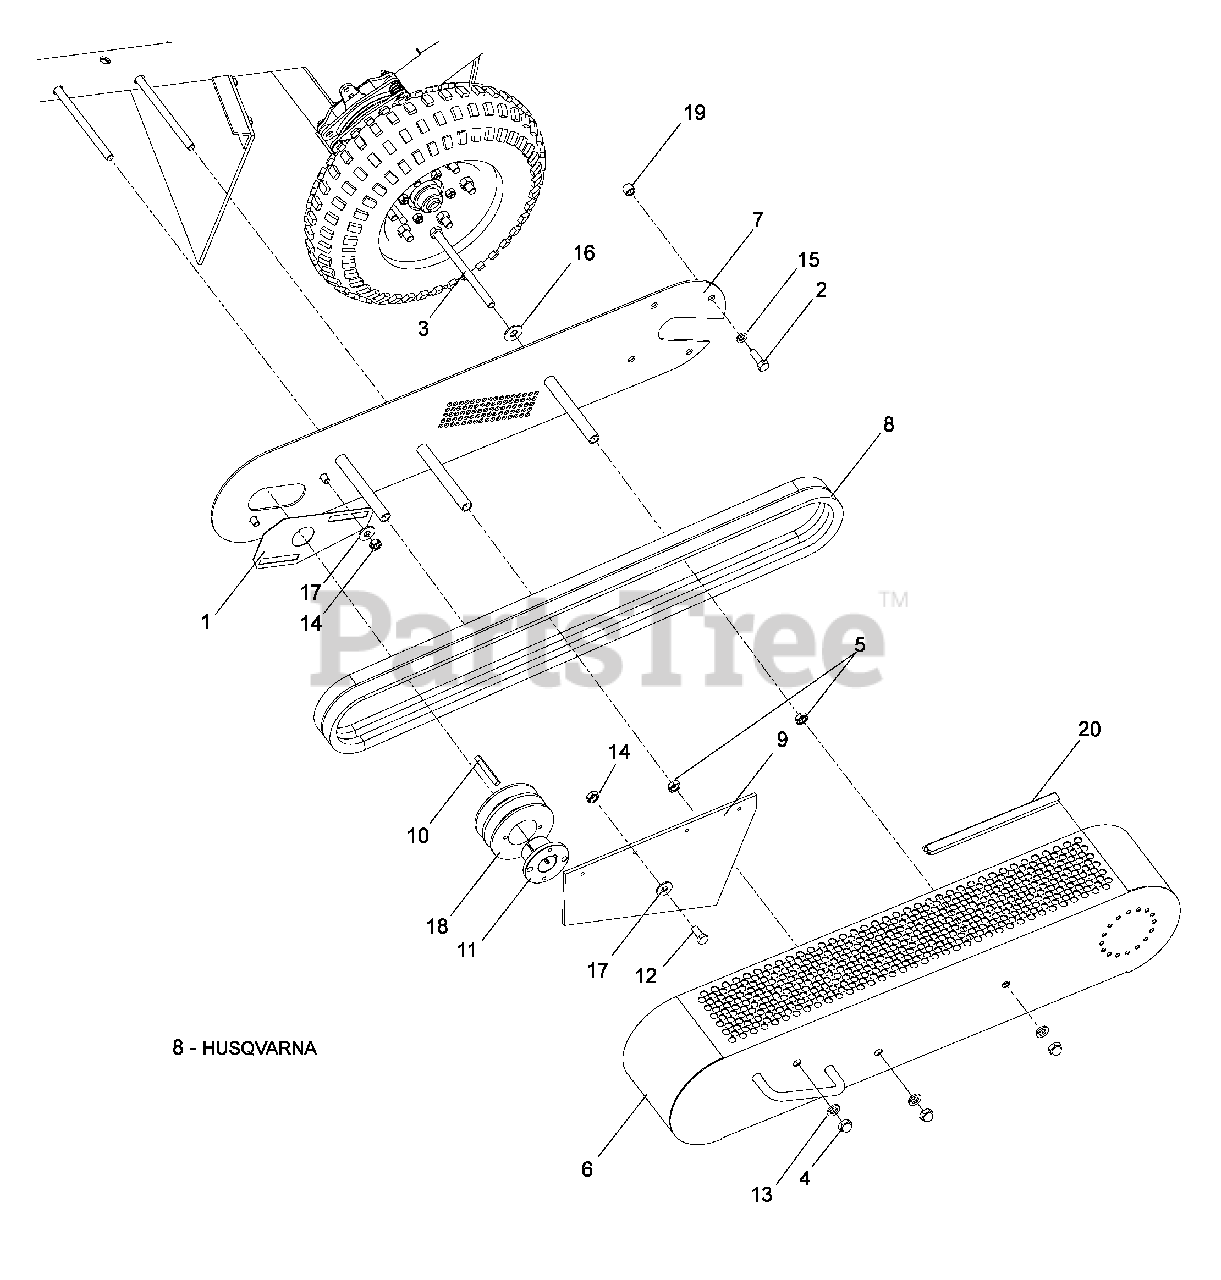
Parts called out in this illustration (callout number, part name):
1	PLATE COVER
2	HCS 5/16-24 x 1
3	HCS ¾-16 x 5½
4	NUT 3/8-16 ACORN
5	NUT 3/8-16 JAM
6	COVER, BELT, w/ TRIM
7	BACK PLATE, BELT GUARD
8	BELT, SET OF 2
9	DEFLECTOR, LEFT SIDE
10	KEY ¼ SQ x 2
11	BUSHING, TAPERLOCK
12	HCS 5/16-18 x ¾
13	WASHER 3/8 SPLIT LK
14	NUT 5/16-18 CNTRLK
15	WASHER 5/16 SLW
16	WASHER 3/8 FLAT STD
17	WASHER 5/16
18	PULLEY, TAPERLOCK
19	SPACER, PULLEY
20	TRIM, FLEX
